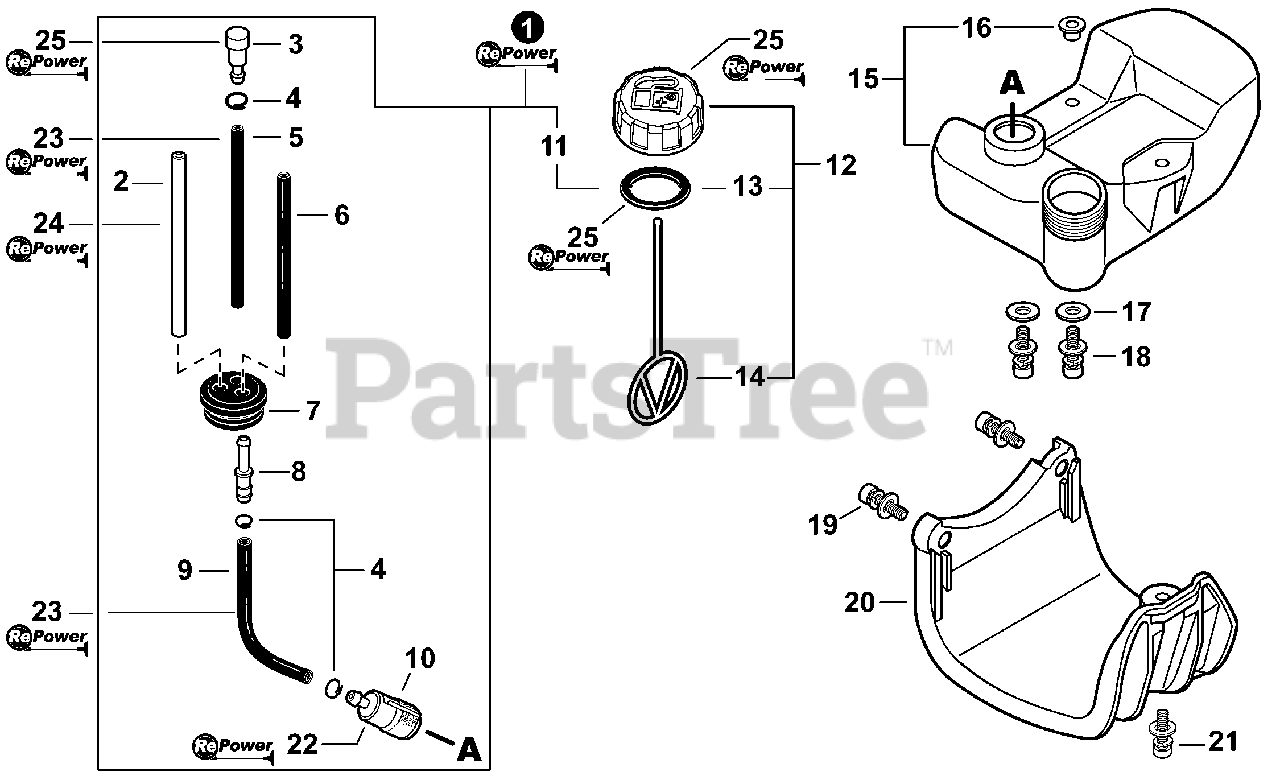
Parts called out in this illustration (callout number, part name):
1	FUEL SYSTEM KIT
2	PIPE, FUEL 3×6×80 CLEAR
3	VENT ASSY
4	CLIP Ø6.5 MM
5	PIPE 3×6×115 BLACK
6	PIPE, FUEL 3×5×74 BLACK
7	GROMMET, FUEL
8	CONNECTOR, PIPE Ø5ר3.5
9	PIPE, FUEL 3×6×100
10	FILTER, FUEL
11	GASKET, FUEL CAP
12	CAP ASSY, FUEL
13	GASKET, FUEL CAP
14	CONNECTOR, CAP L= 100 MM
15	TANK, FUEL
16	COLLAR 5
17	WASHER 5.5×12×0.8
18	BOLT 5×18
19	BOLT 5×22
20	GUARD, FUEL TANK
21	SCREW 5×20
22	TUNE-UP KIT - REPOWER
23	BULK PIPE - 3×6 MM BLACK (4 PIECES×2 M)
24	BULK PIPE - 3×6 MM CLEAR (4 PIECES×2 M)
25	CAP/VENT KIT - REPOWER
